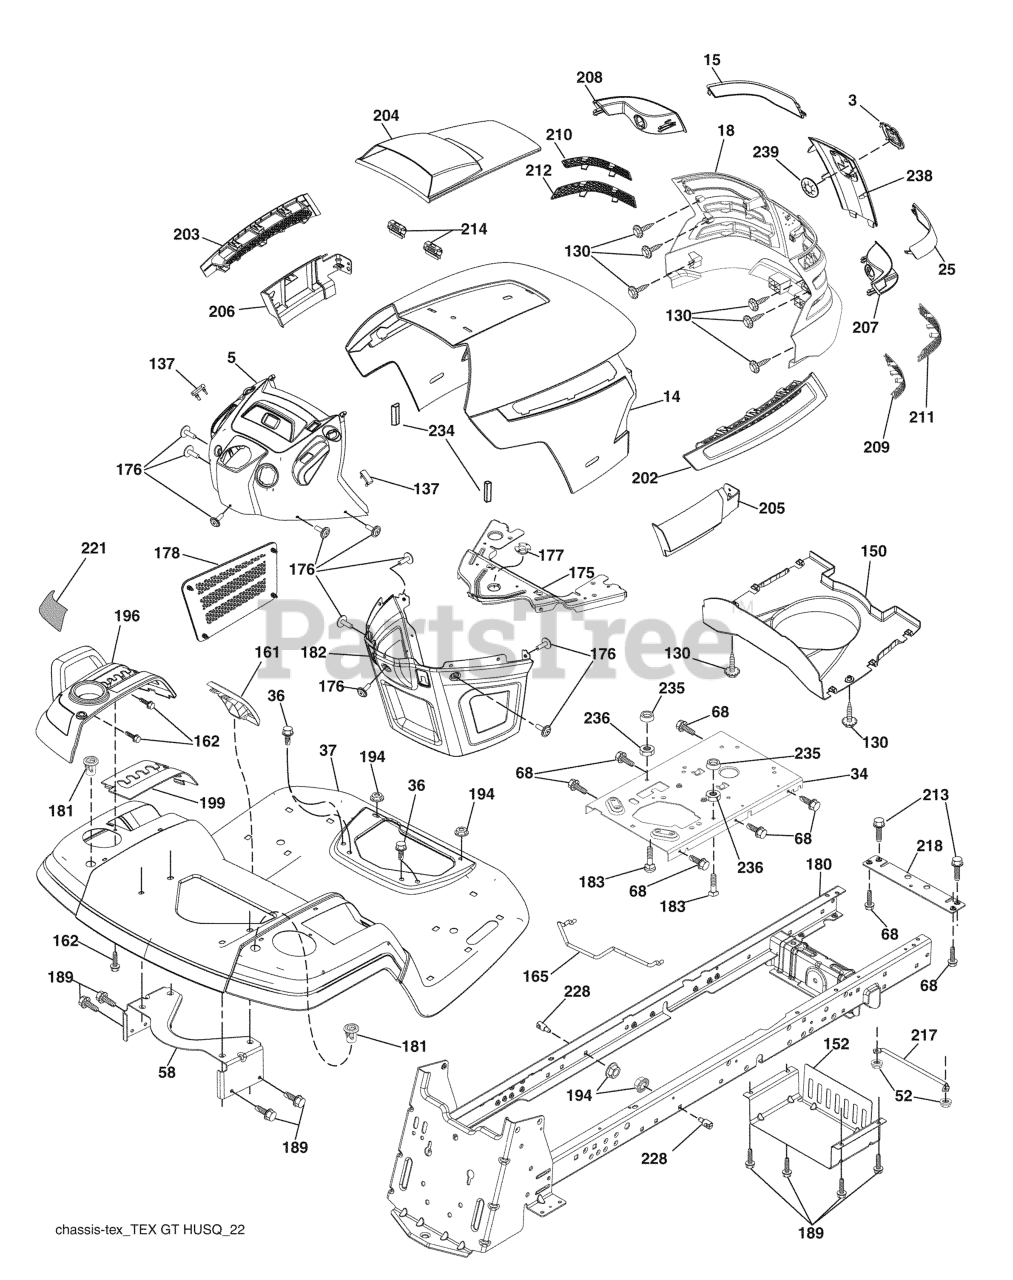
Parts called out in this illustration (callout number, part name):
3	RP LOGO
5	DASH.HUSQ.GT.
14	HOOD
15	LENS.LH.TEX.GT.HUSQ.CL
18	GRILL.ASM.HUSQ.TG/CRD.W/TRIM
25	LENS.RH.TEX.GT.HUSQ.CL
34	PLATE.ENGINE.WELDED.CHASSIS
36	SCREW 5/16"
37	FENDER.PNT.TX.GT.CH/FW.ORANGE
52	LOCKNUT
58	BRKT.SUPPORT.FNDR/TANK
68	Screw 5/16-18 x 1/2
130	SCREW.#10 X 0.750.BOS
137	BUMPER DASH
150	AIR.DUCT.HOOD.TEX.GT.HUSQ
152	SHIELD.BROWNING.W/TEX
161	CONSOLE.FUEL.WINDOW.HU
162	SCREW.HI-LO.CONSOLE
165	SUPPORT.TANK.REAR.W/TEX
175	PLATE.CROSSMEMBER.HUSQ
176	SCREW.#10-24X5/8.RN.QU
177	BUSHING, STEERING
178	CARGO.ASM.NET.TXGT.W/C
180	CHASSIS.GT.SLOPED.DRAWBAR.
181	BUSHING.MNT.FEND.CRGO.
182	DASH.LOWER.COMMON.12V.ADAPTOR
183	BOLT.5/16-18X1-1/4 FULL.THREAD
189	SCREW
194	NUT LOCK HEX FLANGE 5/16-18
196	RP CONSOLE.ASM.DECKLFT.W/
199	PLATE.DECK.LIFT.HUSQVARNA.GT
202	VENT.SIDE.HOOD.HUSQ.RH.GREY
203	VENT.SIDE.HOOD.HUSQ.LH.GRAY
204	HOOD VENT
205	SKIRT.HOOD.SIDE.HUSQ.RH.GREY
206	SKIRT.HOOD.SIDE.HUSQ.LH.GREY
207	BEZEL.RH.TEX.GT.HUSQ
208	BEZEL.LH.TEX.GT.HUSQ
209	INSERT.HEX.GRILL.HUSQ.GREY
210	INSERT.HEX.GRILL.HUSQ.
211	INSERT.HEX.GRILL.HUSQ.
212	INSERT.HEX.GRILL.HUSQ.
213	BOLT
214	CLIP.RETAINER.TINNER.
217	ROD.PIVOT.HOOD
218	X-PIECE.HOOD.STOP.NON/
221	REFLECTOR.LH.TEX GT HU
228	STUD.FASTNER.W/ANTI-ROTATE
234	BUMPER.HOOD.TEX.HUSQVARNA
235	SPACER FENDER
236	NUT.CENTERLOCK.5/16-
238	TRIM.HUSQ.TG/CRD.SERVICE
239	NUT PUSH M
